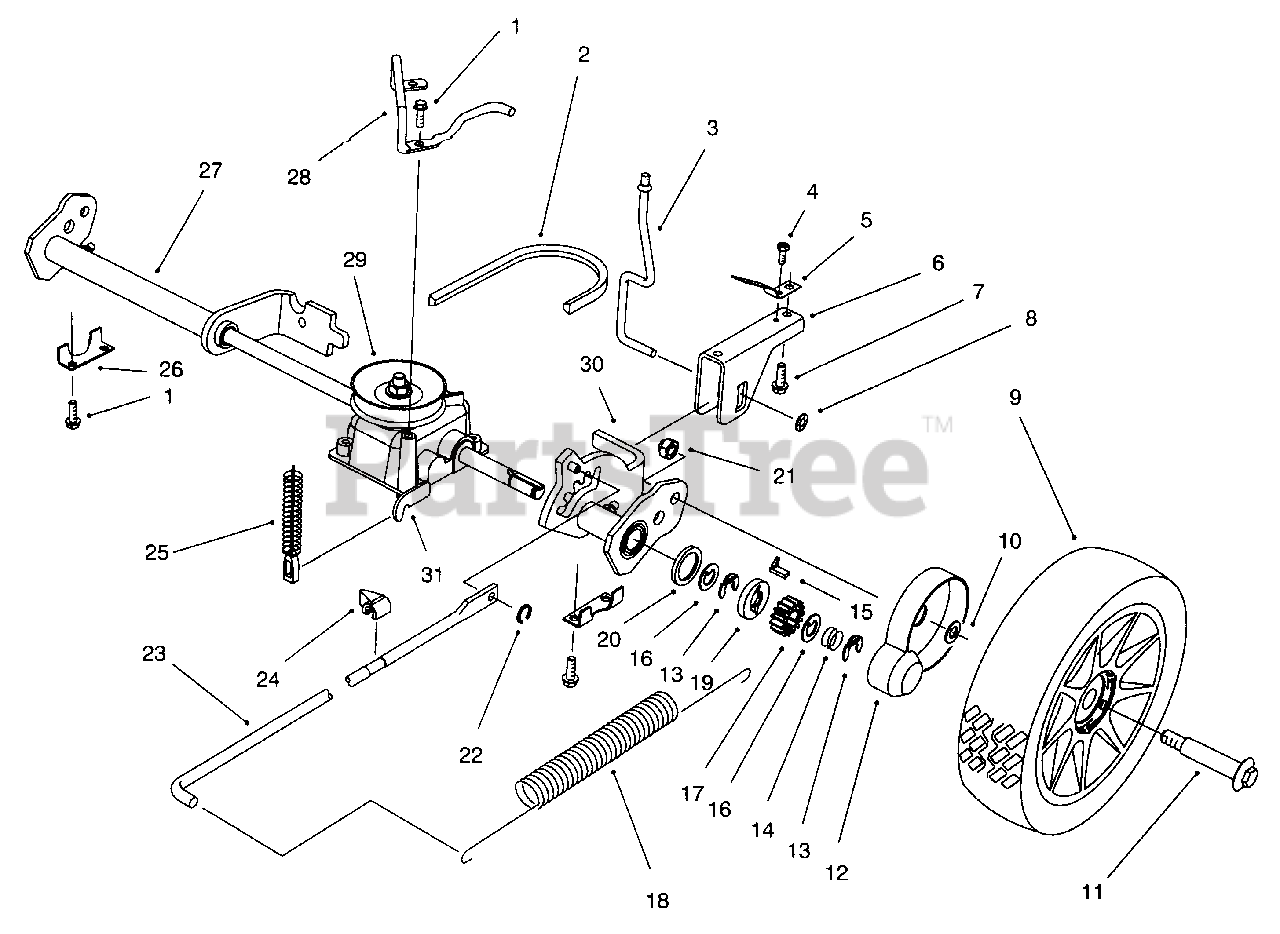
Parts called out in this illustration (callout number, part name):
1	Screw-Tapping
2	V-Belt-Gear Case
3	Rod-Trigger
4	Screw-Tapping
5	Spring-Trigger Retainer
6	Saddle-H.O.C.
9	Wheel & Tire Assembly
10	Spacer-Wheel
11	Bolt-Shoulder
12	Cover-Wheel
13	Ring-Retaining
14	Spring-Compression
15	Key-Rocking L.H.
16	Washer-Thrust Keyed
17	Gear-Pinion
18	Spring-Counterbalance
20	Ring-Friction
21	Nut-Lock
22	Ring-Grip
23	Rod-Link
24	Indicator-H.O.C.
25	Spring-Compression
26	Plate-Securing Rear
27	Arm-R.H. Pivot
28	Retainer-Belt
29	Case-Gear
30	Arm-L.H. Pivot
31	Bracket-Traction
